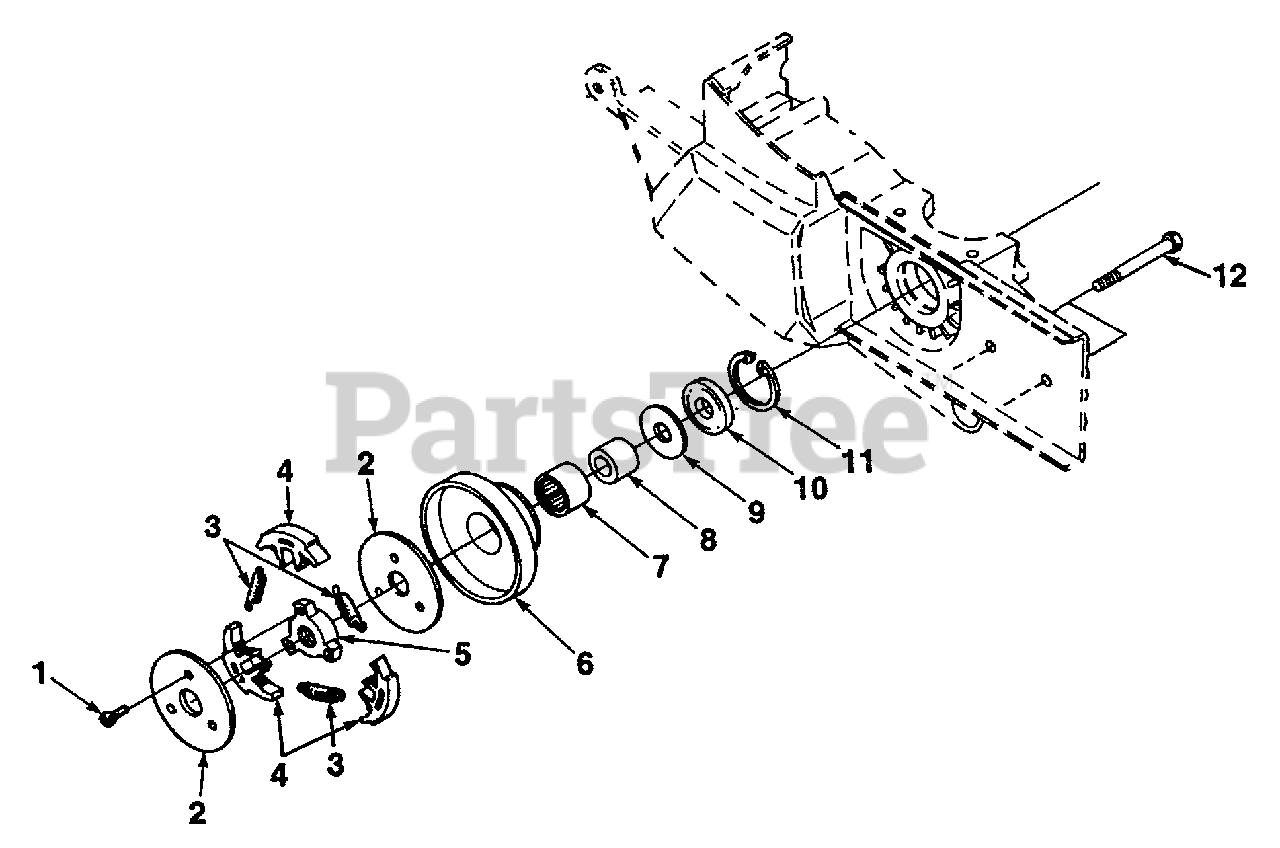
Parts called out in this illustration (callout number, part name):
1	SCREW-Machine Hex Hd. (8-32 X 3/8")
2	COVER-Clutch
3	SPRING-Clutch
4	SHOE-Clutch
5	CLUTCH-Spider
6	PULLEY-Drum & Bearing
7	BEARING-Needle
8	RACE-Inner
9	WASHER-Thrust
10	SEAL-Main
11	RETAINER-Bearing
12	BOLT-Wheel Arm
